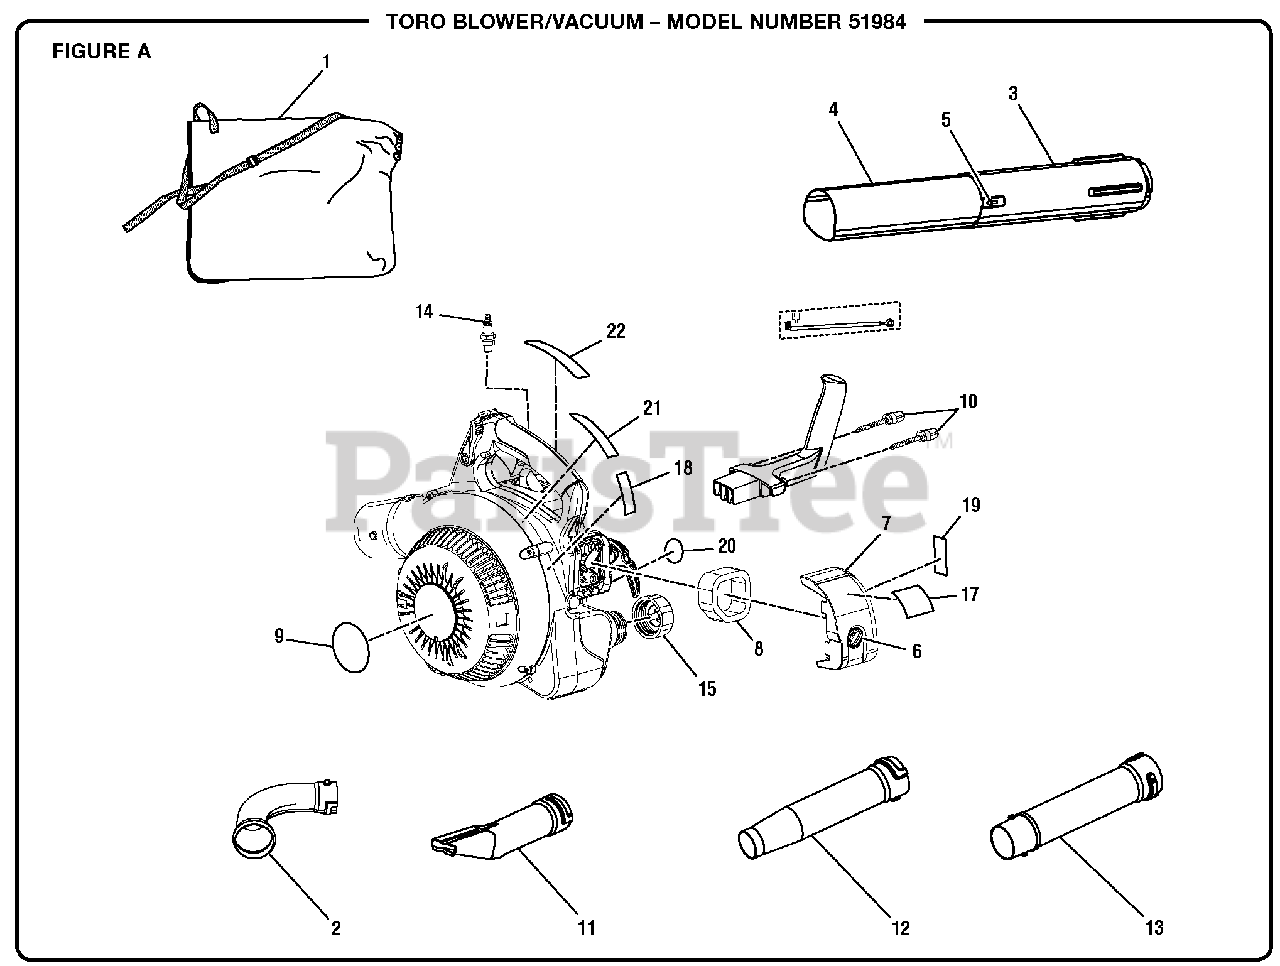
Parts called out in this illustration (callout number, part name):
1	Vacuum Bag w/Shoulder Strap
2	Vacuum Bag Adaptor
3	Upper Vacuum Tube
4	Lower Vacuum Tube
5	Vacuum Tube Screw
6	Knob
7	Air Filter Cover
8	Air Filter
9	Vacuum Door Label
10	Vacuum Handle Knob
11	High Velocity Nozzle w/ Leaf Scraper
12	Sweeper Nozzle
13	Upper Blower Tube
14	Spark Plug (Champion RCJ4)
15	Fuel Cap Assembly
16	Ground Wire Kit
17	Starting Instructions Label
18	"Impeller" Label
19	Choke Label
20	Starter Cover Label
21	"Metal" Label
22	Icon Strip
